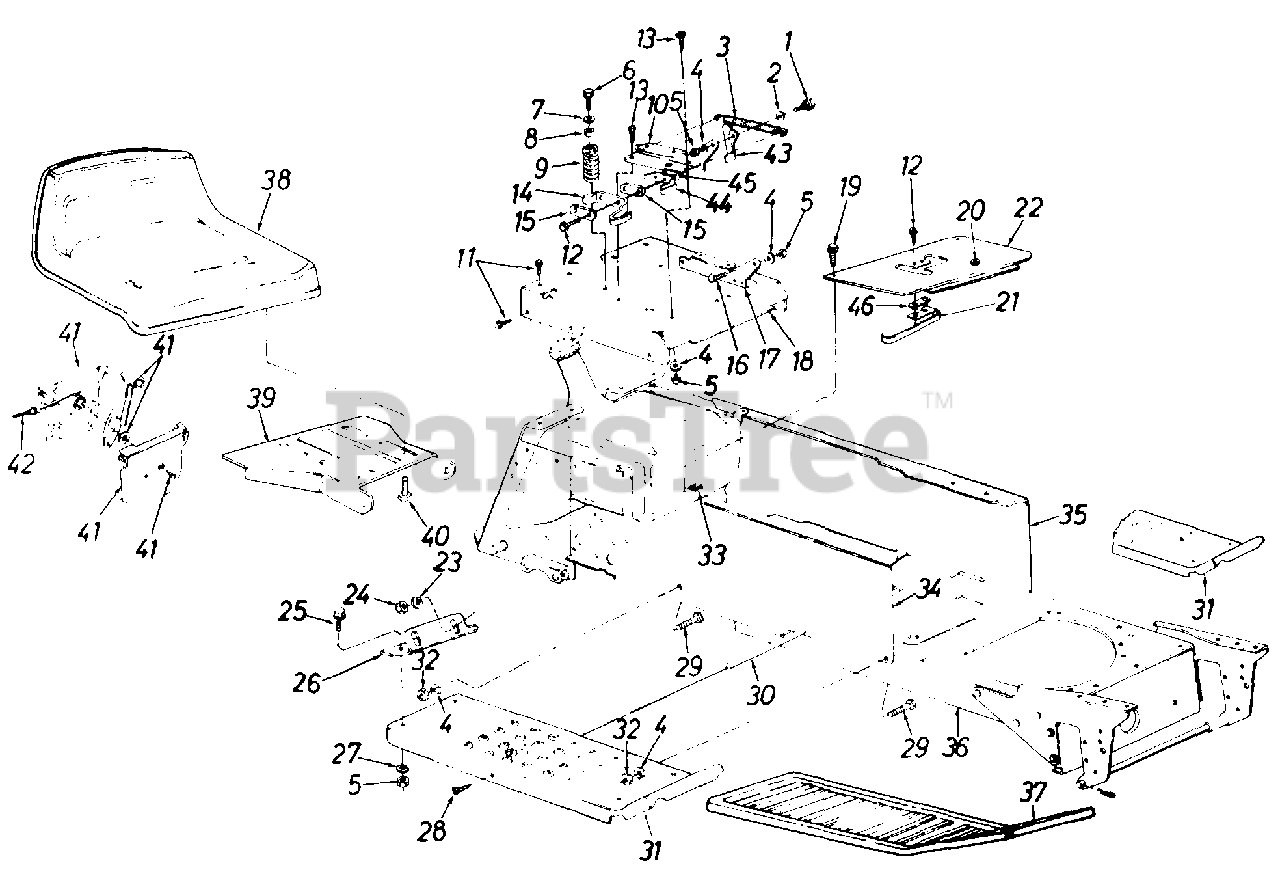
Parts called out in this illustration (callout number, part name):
1	Shld. Bolt .437" Dia. x .162"
2	Spr. Wash. .445" I.D.
3	Ext. Spring 5.31" Lg.
4	L-Wash. 5/16" I.D.
5	Hex Nut 5/16-18 Thd.
6	Hex Wash. Hd. Tap Scr. 5/16-18 x .7" Lg.
7	Fl-Wash. .344" I.D.
8	Bushing
9	Compression Spring
12	Hex Wash. Hd. AB-Tap Scr. #8 x .5" Lg.
13	Torx Hd. AB-Tap Scr. 5/16-18 x .75" Lg.
14	Spring Switch
15	Insulator Plate
16	Shld. Bolt .437" Dia. x .162"
20	Snap Bushing
21	Reverse Safety Switch
22	Shift Cover
23	L-Wash. 1/4" I.D.
24	Hex Nut 1/4-20
25	Hex Bolt 5/16-18 x .75" Lg.
28	Truss Mach. Scr. 5/16-18 x .75" Lg.
29	Rib Neck Bolt 5/16-24 x .75" Lg.
30	Running Board Rod
33	Speed Nut #10Z
34	R.H. Side Frame
37	Rubber Foot Pad
38	Seat 8-7/8" High
39	Seat Pivot Bracket
40	Hex Tap Scr. 3/8-16 x .75" Lg.
41	Throttle Control Box Ass'y.
42	Throttle Control Wire 35" Lg.
43	Seat Lift Bracket
44	Seat Spring Switch
45	Insulator Boss Plate
46	Insulator Nut Plate
